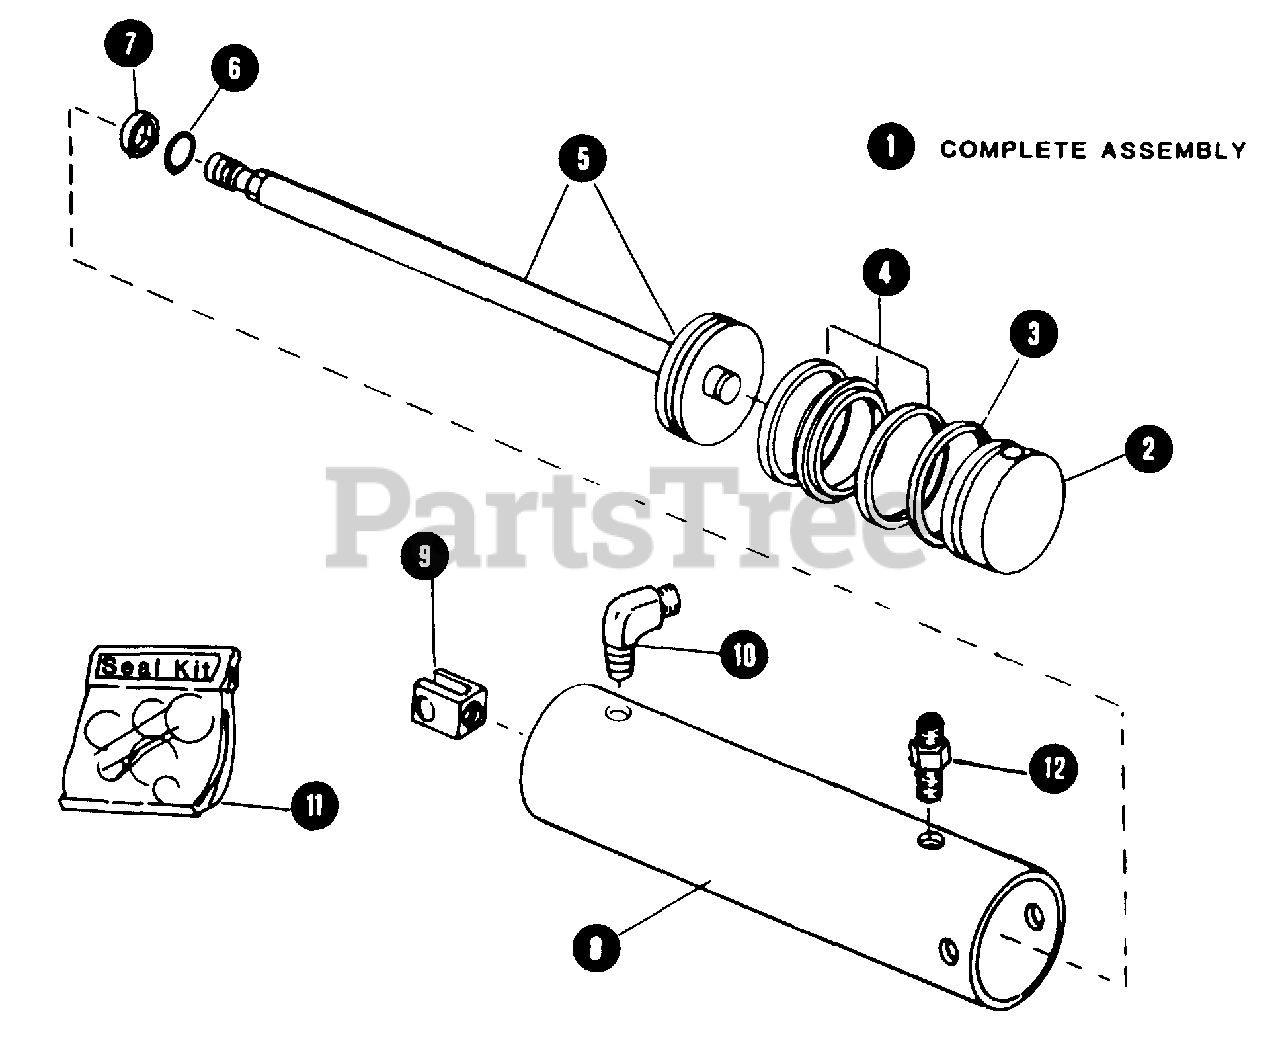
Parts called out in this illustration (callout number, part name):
1	CYLINDER MID-MOUNT LIFT ASSEMBLY
2	HEAD, CYLINDER
3	PACKING, CYLINDER HEAD
4	SEAL-RING ASSEMBLY, PISTON BACK-UP
5	PISTON-ROD ASSEMBLY
6	O-RING, PISTON ROD
7	SEAL, PISTON
8	TUBE, CYLINDER
9	FITTING, PISTON ROD END
10	ELBOW, 1/4P.T. - 90 Degree
11	KIT, SEAL REPLACEMENT
12	FITTING, CONNECTOR 1/4P.T. x 9/16-18 STRAIGHT THREAD
